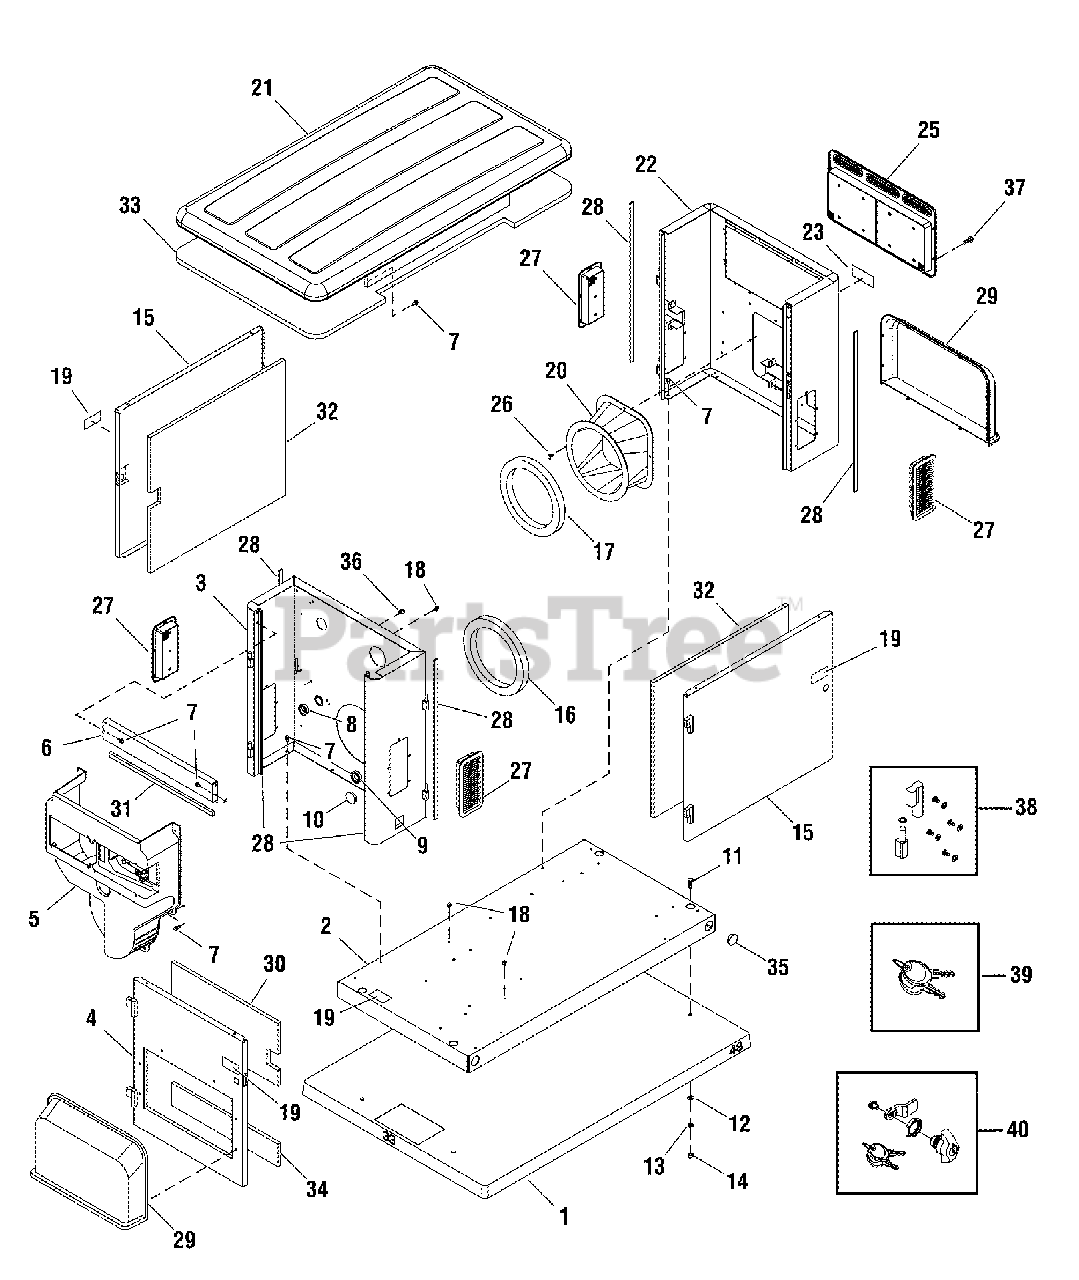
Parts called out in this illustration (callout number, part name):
2	BASE
3	BULKHEAD, Engine
7	BOLT
11	* CAPSCREW, Hex Head, 3/8-16 x 1
12	* WASHER, Flat, 3/8-M10
13	* WASHER, Lock, 3/8
14	* NUT, 3/8-16
20	ADAPTER, Engine
22	BULKHEAD, Alternator
29	COVER, Air Intake
37	SCREW
